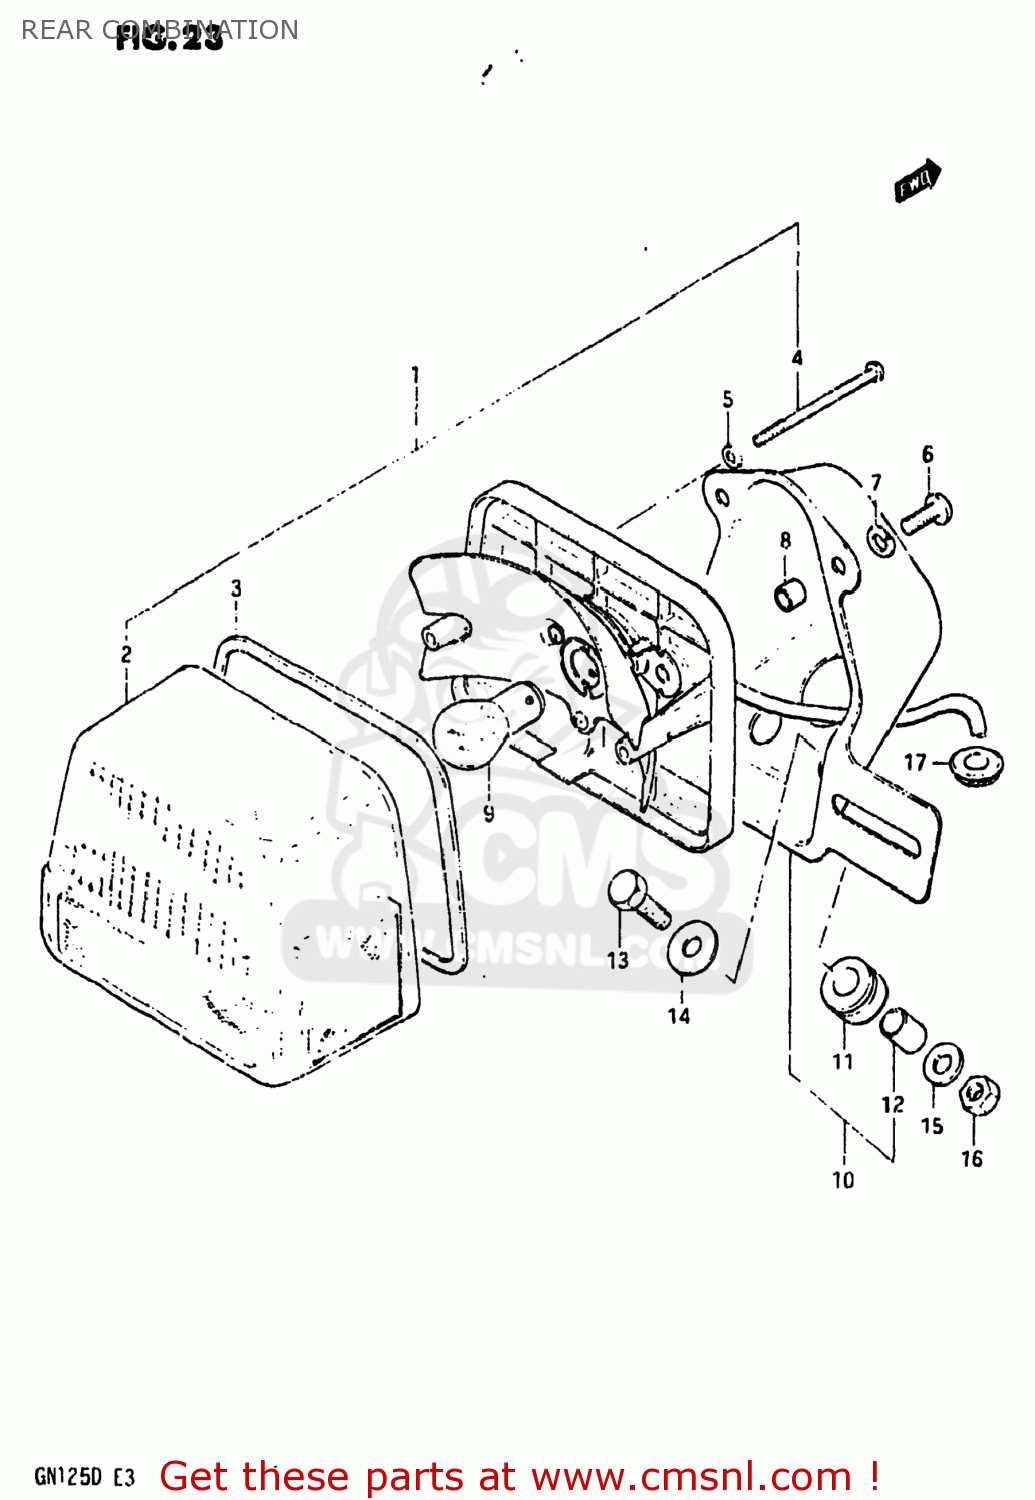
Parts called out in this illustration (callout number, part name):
1	LAMP UNIT,REAR COMBINATION
2	LENS
3	GASKET (NAS)
4	SCREW
5	GASKET (NAS)
6	SCREW
7	LOCK WASHER
8	SPACER
9	BULB(12V23W)
10	BRACKET UNIT,TAIL LAMP
11	CUSHION
12	SPACER
13	BOLT
14	WASHER (6.5X20X1.2)
15	WASHER
16	NUT
17	GROMMET
